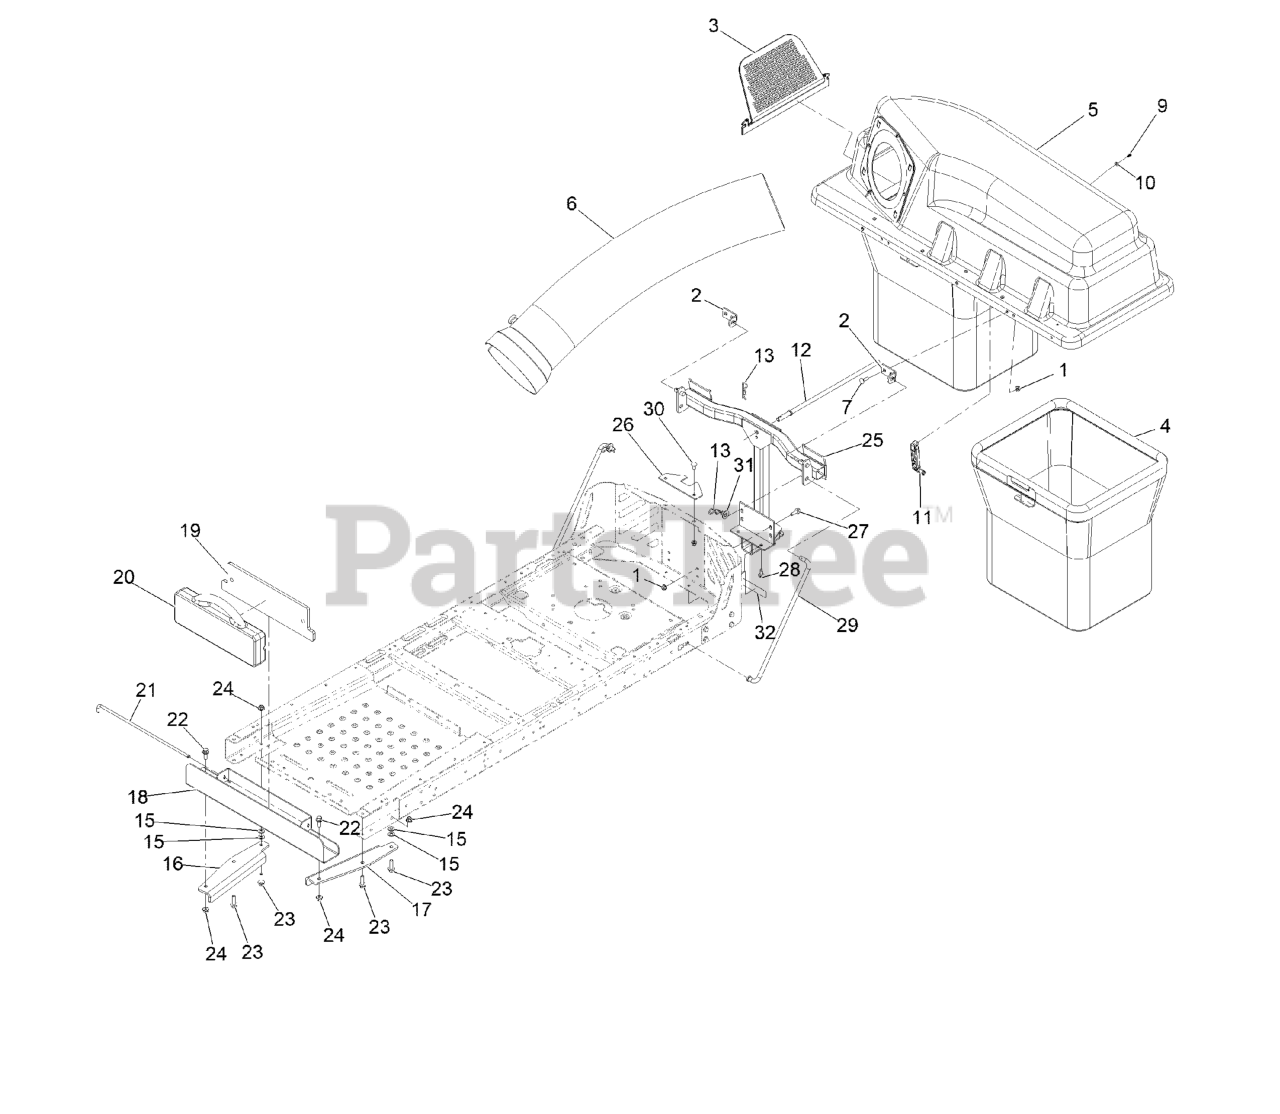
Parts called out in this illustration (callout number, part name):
1	NUT-HF, NI
2	BRACKET-PIVOT, HOPPER
3	SCREEN-BAGGER
4	BAG ASM
5	BAGGER TOP ASM
6	TUBE-BAGGER
7	BOLT-CARR
9	SCREW-PLASTIC, PTH
10	WASHER-FLAT
11	LATCH-RUBBER
12	ROD-HOOD, DOWN (HOLD)
13	PIN-HAIR
15	WASHER-FLAT
17	BRACKET-BAGGER WEIGHT, LH
18	CHANNEL-WEIGHT, BAGGER
20	WEIGHT-35 POUND
21	PIN-WEIGHT
22	SCREW-HHF 3/8-16 X 1
23	SCREW-HHF
24	NUT-HF, NI
25	Frame ASM, Pivot [black]
26	BRACKET-STABILIZER
27	SCREW-HHF
28	Screw-HWH 5/16-18 X 3/4 Tf
29	ROD-SUPPORT
30	BOLT-CARR
31	WASHER-FLAT
